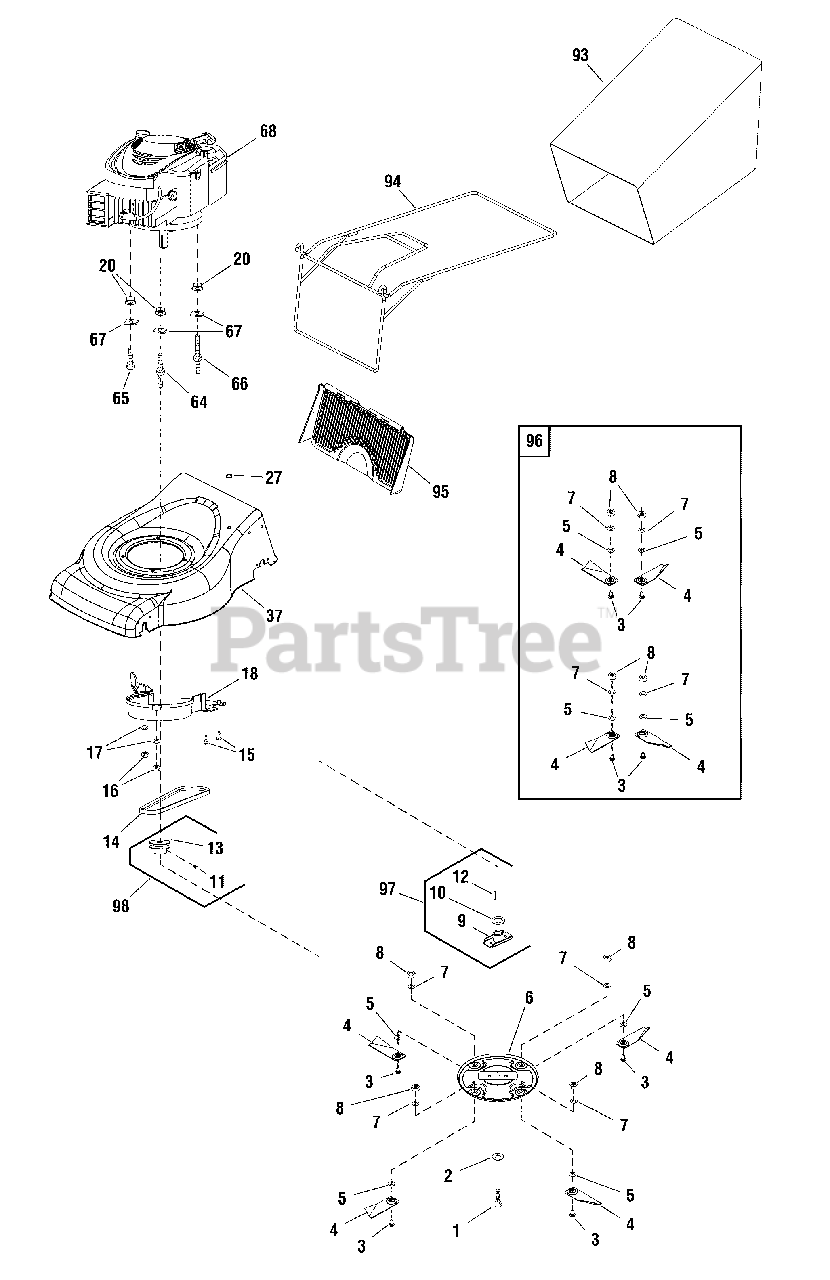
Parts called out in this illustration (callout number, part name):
1	BOLT, Blade
3	BOLT, Blade Disc
5	WASHER, Blade Disc
6	BLADE DISC
7	* WASHER, Flat
8	* NUT, Hex Lock
9	SUPPORT, Blade
10	SLEEVE, Blade Support
11	SET SCREW
16	* NUT, Hex Lock
17	* WASHER, Flat
18	COVER, Belt
20	* NUT, Hex Lock
27	GROMMET
65	* BOLT, Hex
67	WASHER, Square
68	** ENGINE, Briggs & Stratton 650 Series
93	BAG, Grass
95	COVER, Rear
96	KIT, Blade
97	KIT, Blade Adapter
98	KIT, Drive Adapter
